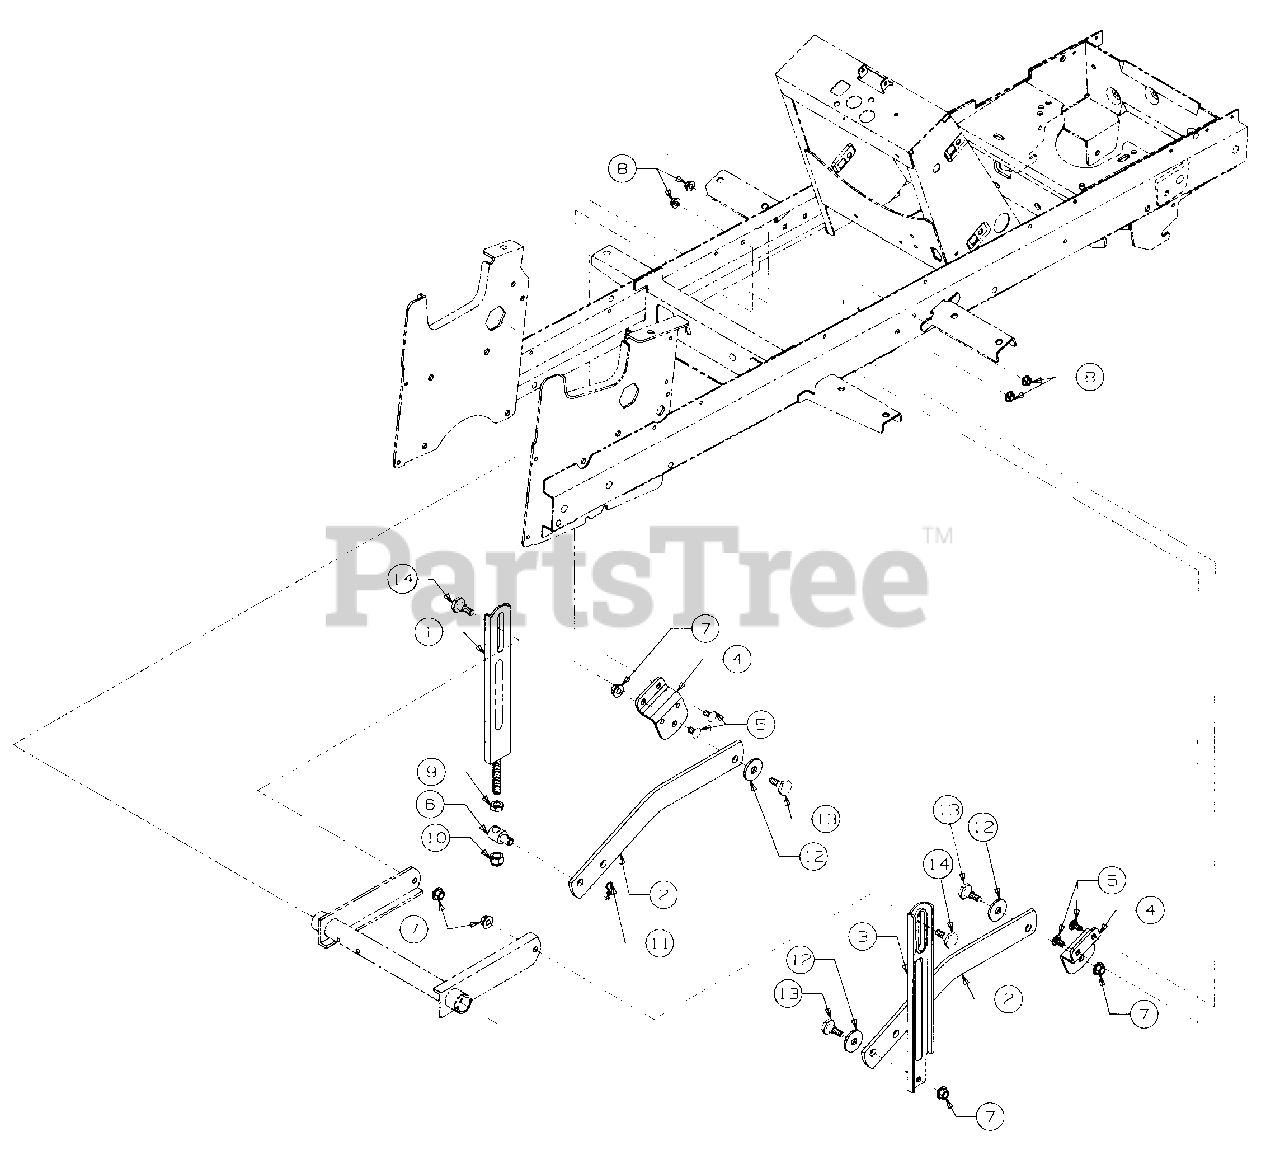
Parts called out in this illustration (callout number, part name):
2	Link, Lift
5	Bolt, Carriage, 5/16-18 x .62 Lg
6	Ferrule, Adjustment
7	Nut, Hex Flanged Lock, 3/8-16
8	Nut, Hex Flange Top Lock 5/16-18
9	Nut, Hex Jam, 1/2-13 GR5
10	Nut, Hex Top Nylon Lock 1/2-13
11	Pin, Internal Cotter, .092 Dia x 1.63 Lg
12	Washer, Flat, .50 x 1.5 x .15 Thk
13	Bolt, Shoulder
14	Bolt, Shoulder
